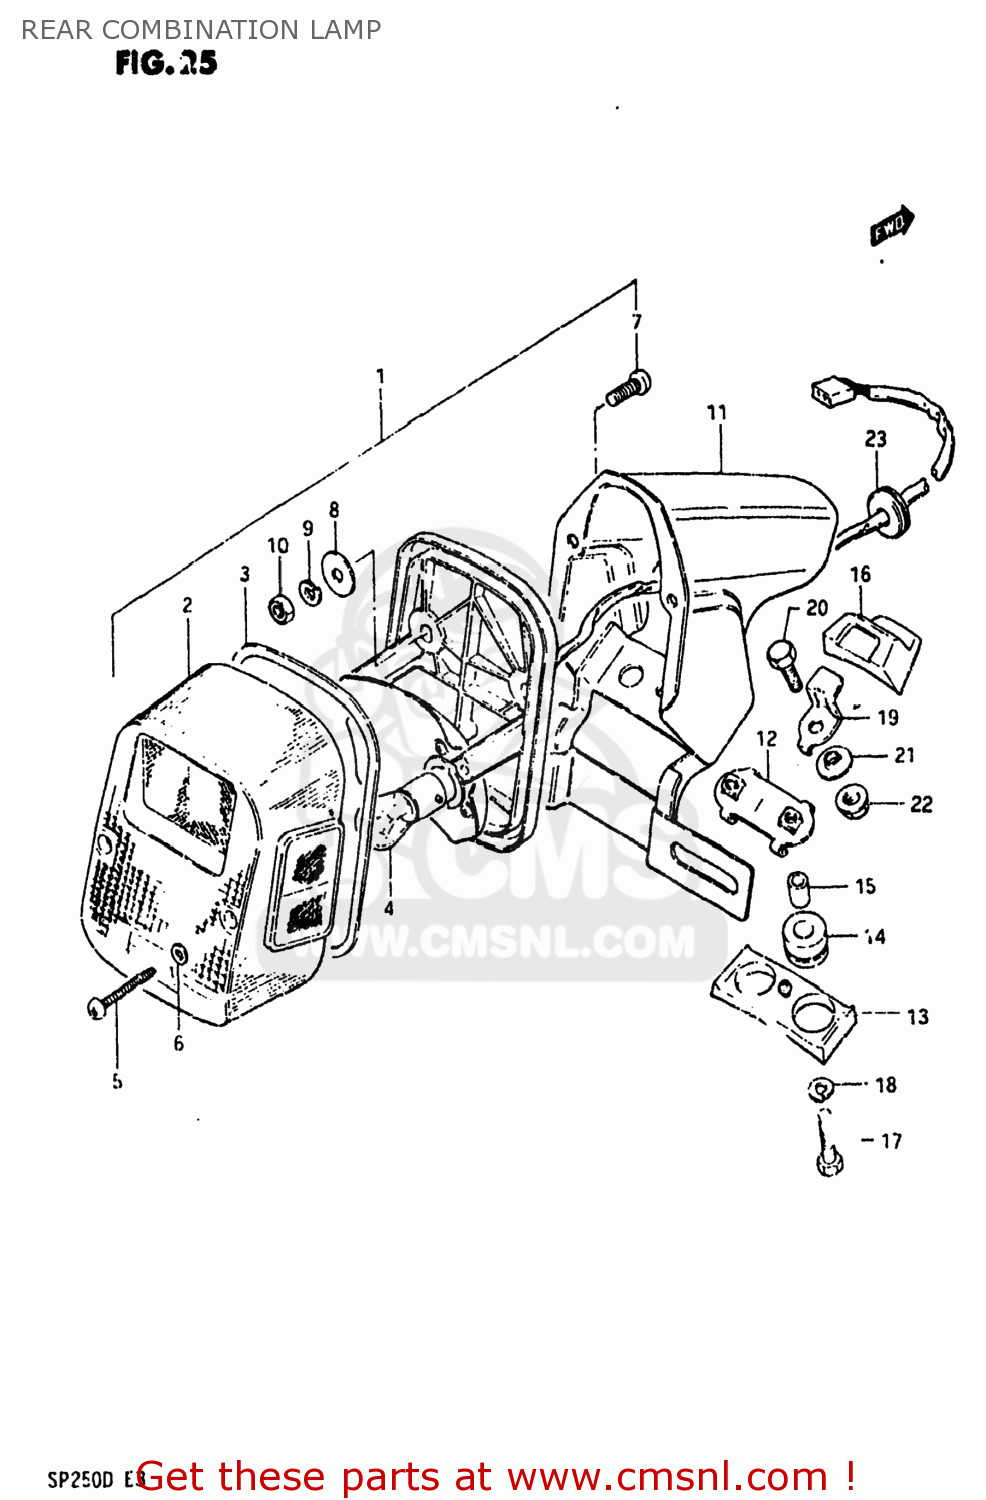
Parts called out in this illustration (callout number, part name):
1	LAMP UNIT,REAR COMBINATION
2	LENS
3	GASKET (NAS)
4	BULB(6V32/3CP,STANLEY)
5	SCREW TAPP.
6	GASKET (NAS)
7	SCREW
8	WASHER,REAR COMBINATION LAMP
9	LOCK WASHER
10	NUT
11	BRACKET UNIT,TAIL LAMP
12	PLATE
13	CUSHION
14	CUSHION
15	SPACER
16	CUSHION,REAR COMBINATION LAMP
17	BOLT
18	LOCK WASHER
19	PLATE,RR COMBINATION LAMP
20	BOLT, UPPER
21	WASHER,LOCK
22	NUT
23	GROMMET
